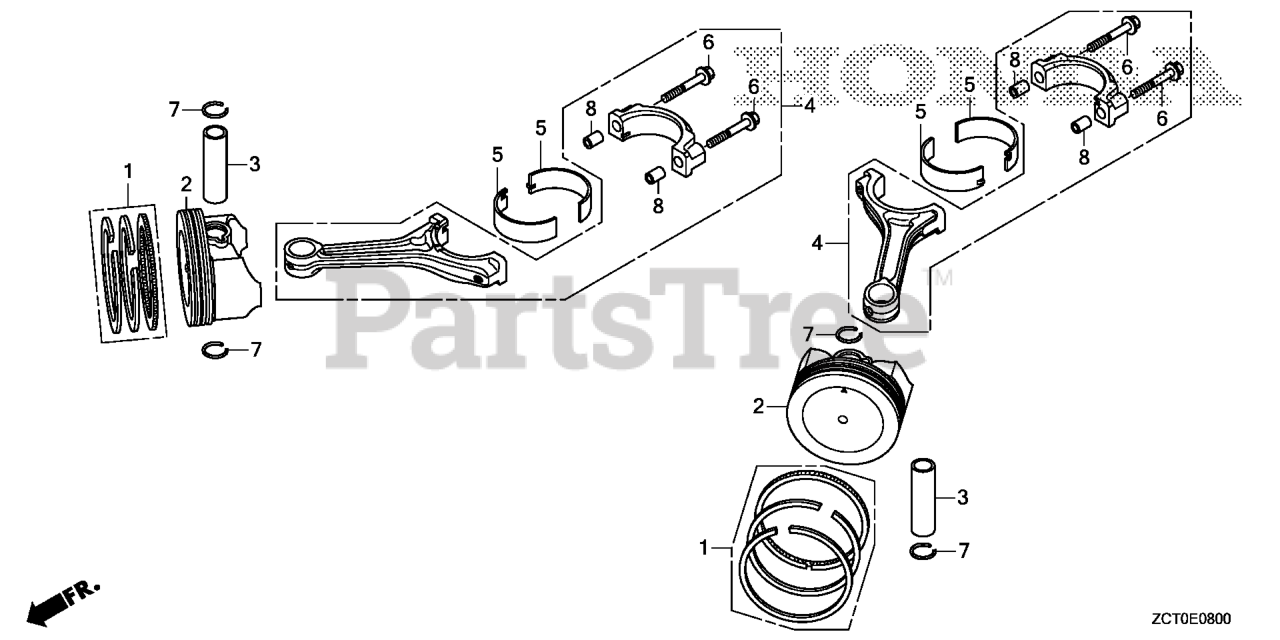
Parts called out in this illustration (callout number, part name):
1	RING SET, PISTON (STD.) (TEIKOKU)
3	PIN, PISTON
4	ROD ASSY., CONNECTING
5	BEARING A, CONNECTING ROD
6	BOLT, CONNECTING ROD (7X38)
7	CLIP, PISTON PIN (18MM)
8	PIN, DOWEL (9X10)
